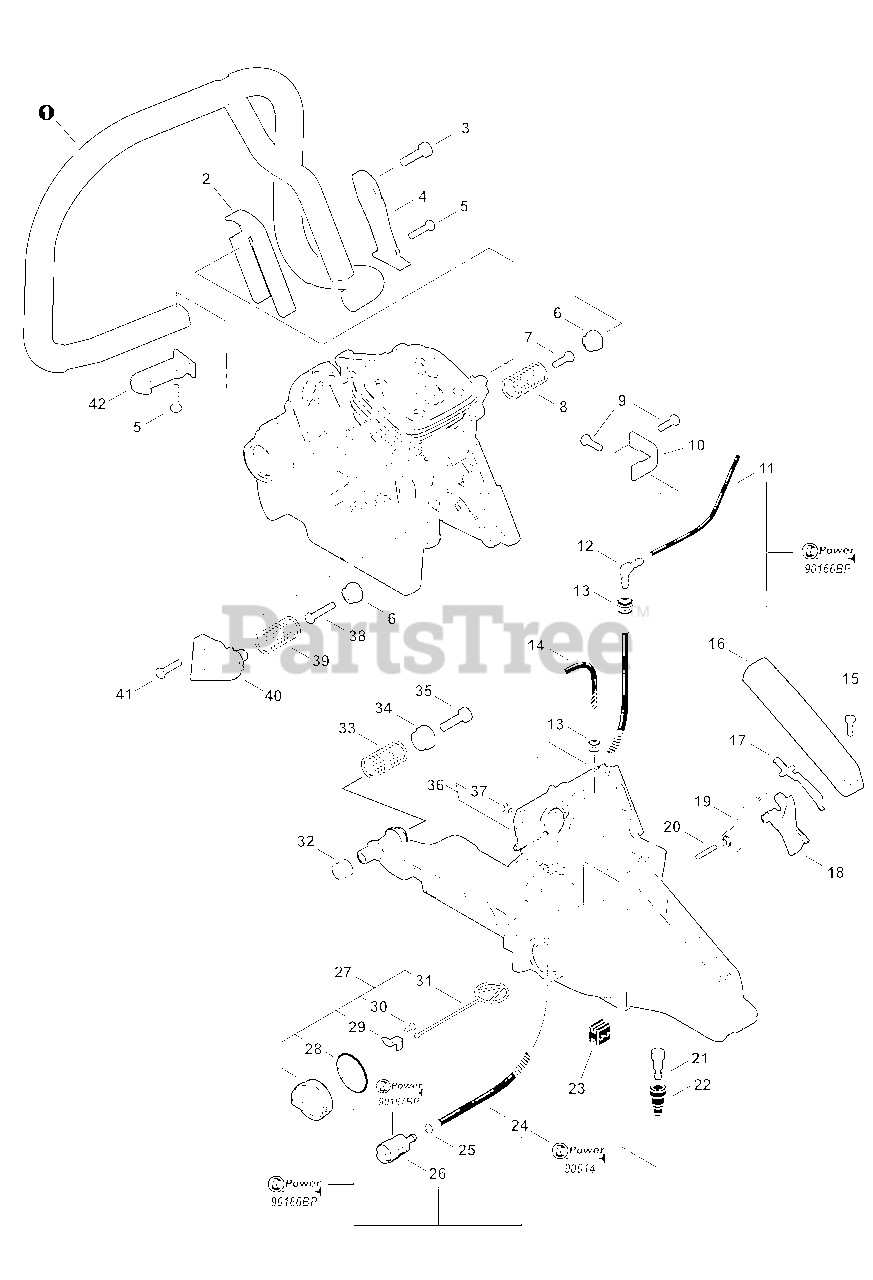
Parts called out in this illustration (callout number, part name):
1	HANDLE, FRONT
2	HOLDER, SPRING
3	BOLT, TORX 6×20
4	BRACKET, HANDLE
5	BOLT, TORX 5×20
6	HOLDER, SPRING Ø14.4
7	BOLT, TORX 5×16
8	SPRING, COMPRESSION Ø17×38.4×2.6
9	BOLT, TORX 5×16
10	STRAP, SAFETY
11	PIPE, FUEL 3×6×135
12	CONNECTOR, PIPE
13	GROMMET
14	PIPE, IMPULSE 3×6(8)×160
15	BOLT, TORX 4×12
16	COVER, HANDLE
17	LEVER, THROTTLE LOCKOUT
18	TRIGGER, THROTTLE
19	SPRING, TORSION
20	PIN, SPRING 4×25 SUS
21	VENT ASSY
22	GROMMET, VENT
23	GROMMET, LEAD
24	PIPE, FUEL 3×5×120 BLACK
25	CLIP Ø6
26	FILTER, FUEL
27	CAP ASSY, FUEL
28	O-RING 29
29	RETAINER, CONNECTOR
30	SCREW, TAPPING 3×8
31	CONNECTOR, CAP L= 60 MM
32	CUSHION 10
33	SPRING, COMPRESSION Ø20×40×3.3
34	HOLDER, SPRING Ø17
35	BOLT, TORX 6×20
36	HANDLE, REAR
38	BOLT, TORX 5×25
39	SPRING, COMPRESSION Ø17×36.7×2.6
40	HOLDER, SPRING
41	BOLT, TORX 5×20
42	MOUNT, HANDLE
